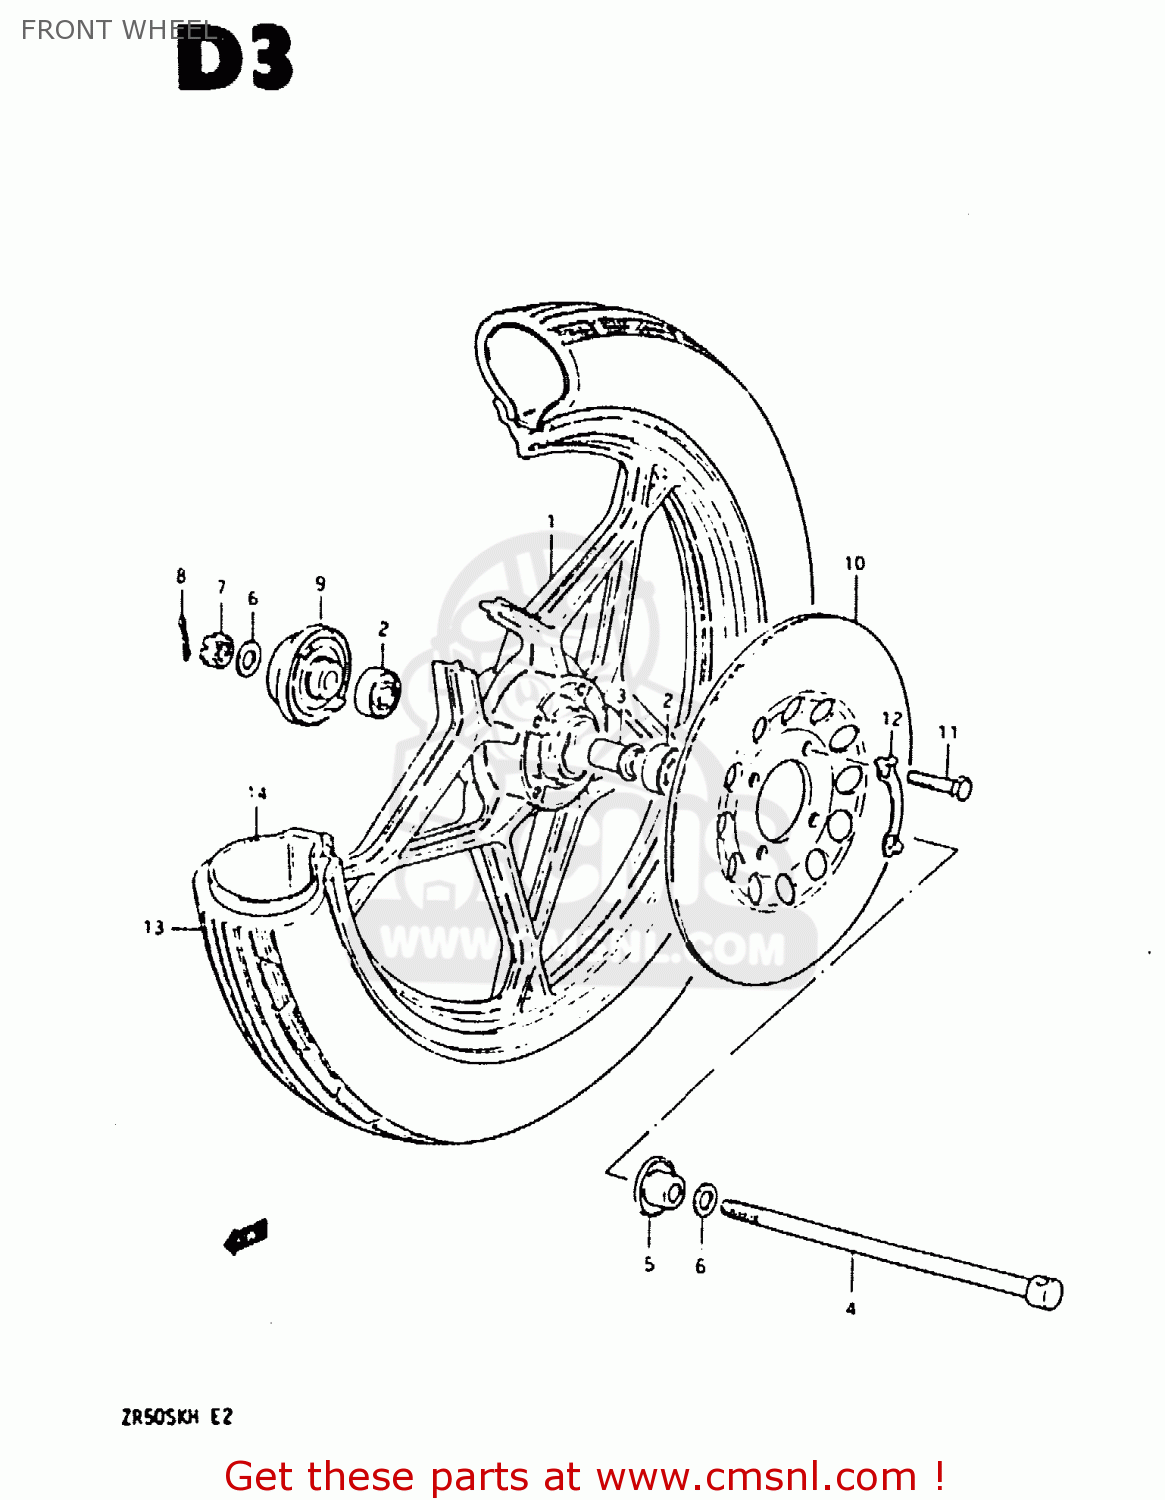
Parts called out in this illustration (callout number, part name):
1	WHEEL, FRONT (140*18) GOLD
2	BEARING
3	SPACER
4	AXLE,FRONT
5	SPACER,FR AXLE,L
6	WASHER(10.5X22X2.3)
7	NUT
8	PIN 20X20
9	BOX, SPPEDOMETER GEAR
10	DISC,BRAKE
11	BOLT(8X30)
12	WASHER
13	TIRE,FR(2.50-18 40L NF2)
14	TUBE,INNER
